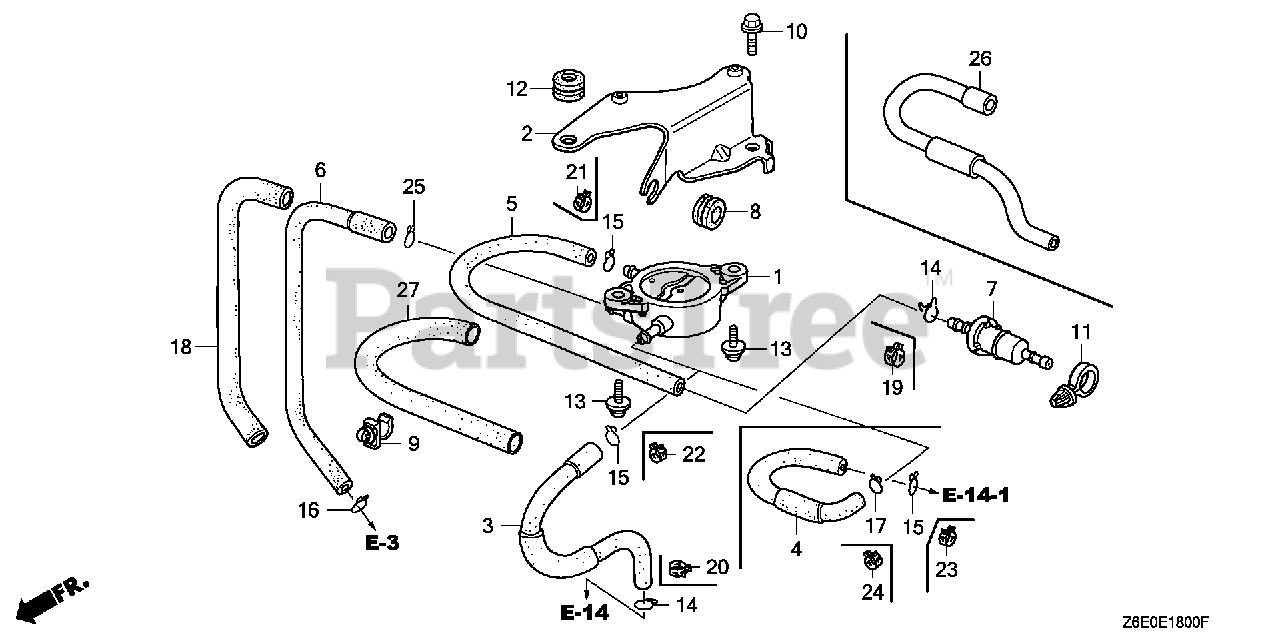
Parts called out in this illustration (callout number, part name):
1	PUMP ASSY., FUEL
2	STAY, FUEL PUMP
3	TUBE A, FUEL (FKM)
6	TUBE, DIAPHRAGM
7	FILTER, FUEL
8	GROMMET, RESERVE TANK
10	BOLT, FLANGE (6X14) (CT200)
11	CLIP, WIRE HARNESS
12	GROMMET, PUMP STAY
13	SCREW-WASHER (6X16)
16	CLIP, TUBE (B8)
18	BULK HOSE, VINYL (9X11X3000) (9X11X150)
19	CLAMP, TUBE (D8)
20	CLAMP, TUBE (D8)
21	CLAMP, TUBE (D8.5)
22	CLAMP, TUBE (D8.5)
25	CLIP, TUBE (B10)
26	TUBE B, FUEL (FKM)
